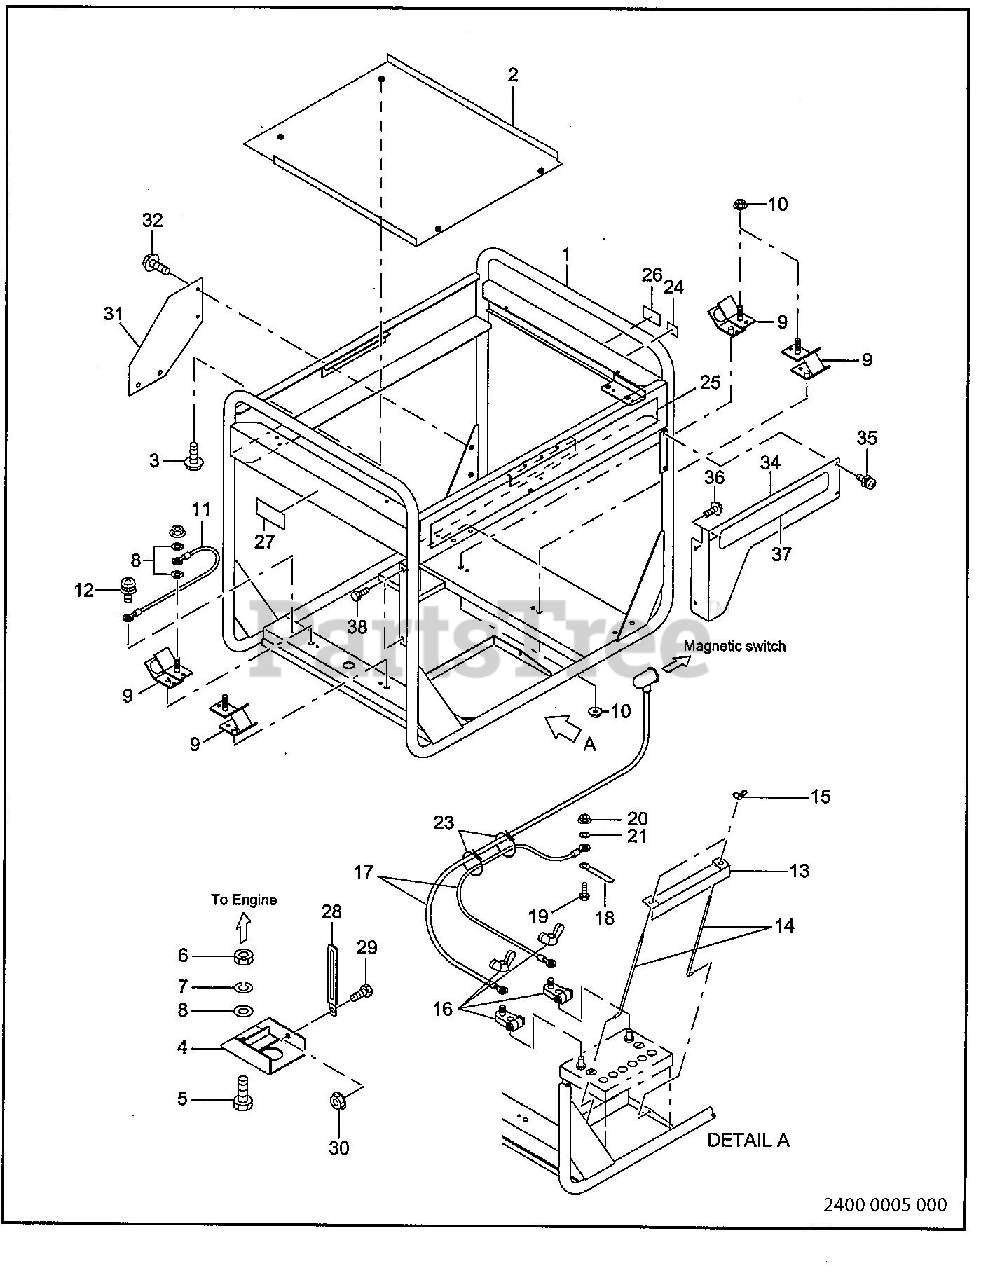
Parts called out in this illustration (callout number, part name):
1	PIPE FRAME ASSY
3	FLANGE BOLT
5	BOLT
10	FLANGE NUT
12	SCREW and WASHER ASSY
13	BATTERY STAY ASSY
16	BATTERY TERMINAL
17	WIRE CABLE SET
19	BOLT
20	FLANGE NUT
24	LABEL (fuel strainer)
25	LABEL (Robin)
27	LABEL (hot & gas)
29	FLANGE BOLT
30	FLANGE NUT
32	FLANGE BOLT
35	SCREW and WASHER
36	FLANGE BOLT
37	LABEL (RGV13100T)
38	FLANGE BOLT
